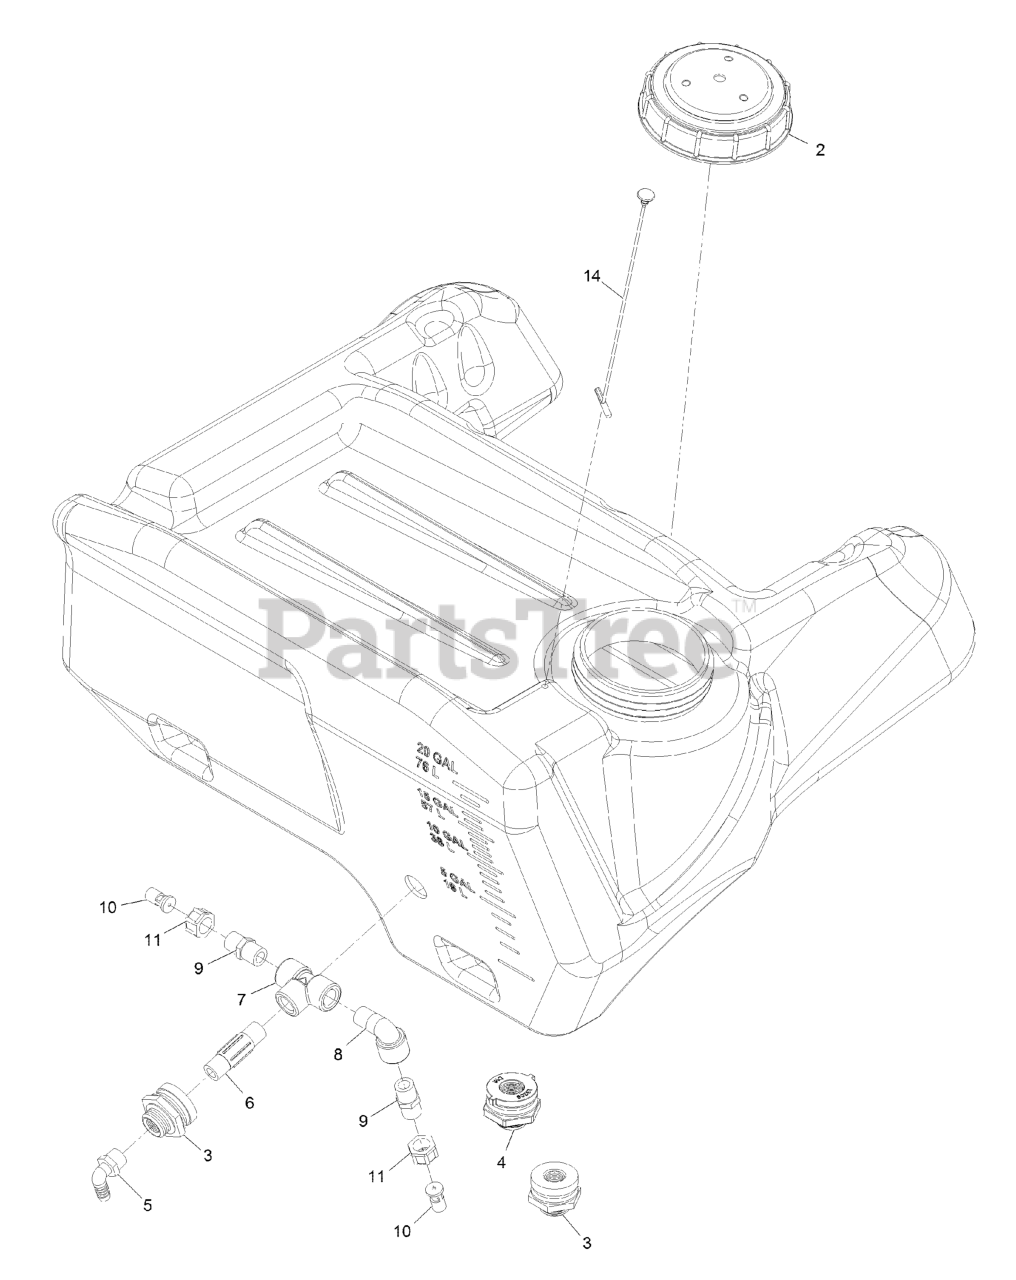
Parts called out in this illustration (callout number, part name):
2	CAP-WATER, 5 INCH VENT
3	FITTING-BULKHEAD
4	FITTING-BULKHEAD
5	ELBOW-90 DEG
8	ELBOW-90 DEG
9	NIPPLE-SHORT
10	NOZZLE-AGITATION
14	LANYARD-CAP, SELF ANCHORI
